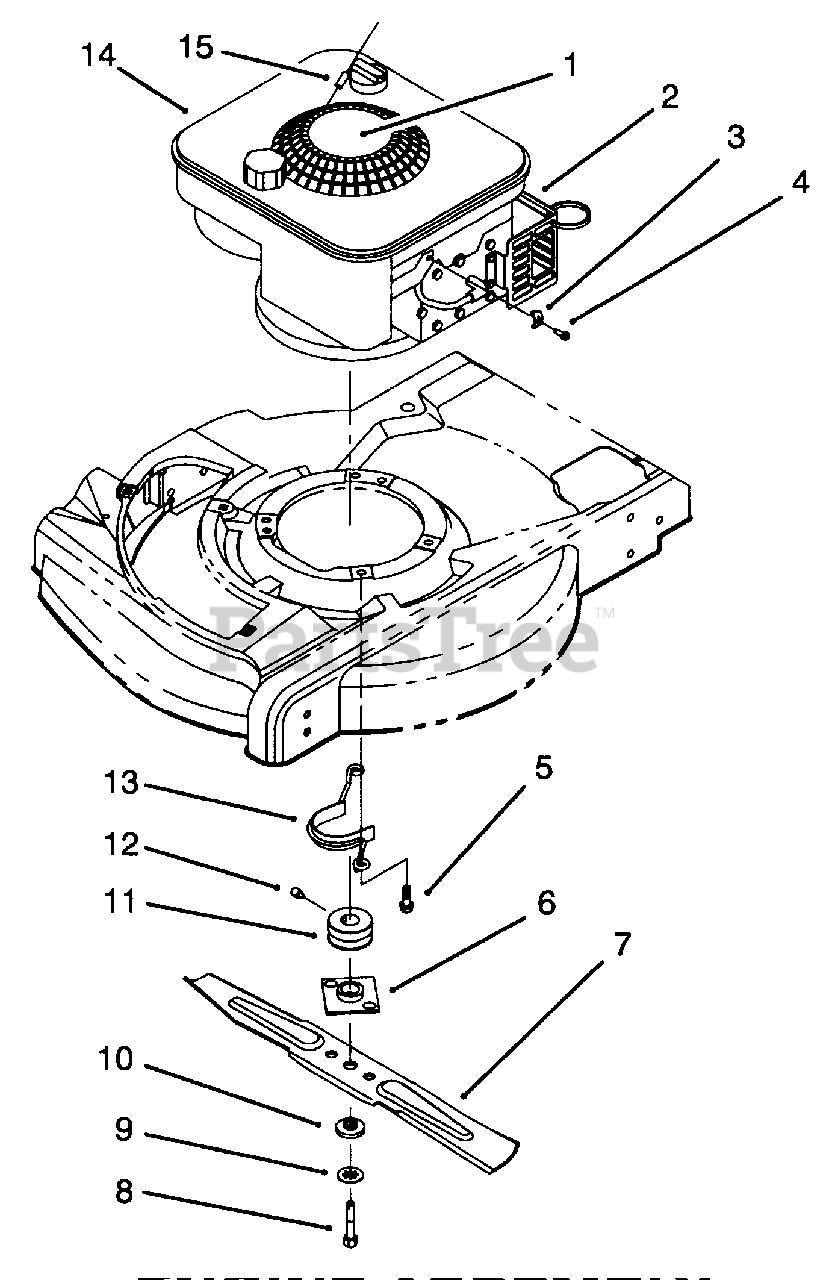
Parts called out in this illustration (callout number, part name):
1	Decal-Shroud
2	Shield-Muffler
3	Clamp-Casing
4	Screw-Clamp
5	Screw-Engine
6	Plate & Collar
7	Blade-21"
8	Bolt-Blade
9	Washer-Lock
10	Spacer-Blade
11	Pulley-Engine
12	Screw-Set
13	Guide-Belt
14	Engine
15	Stop-Rope
